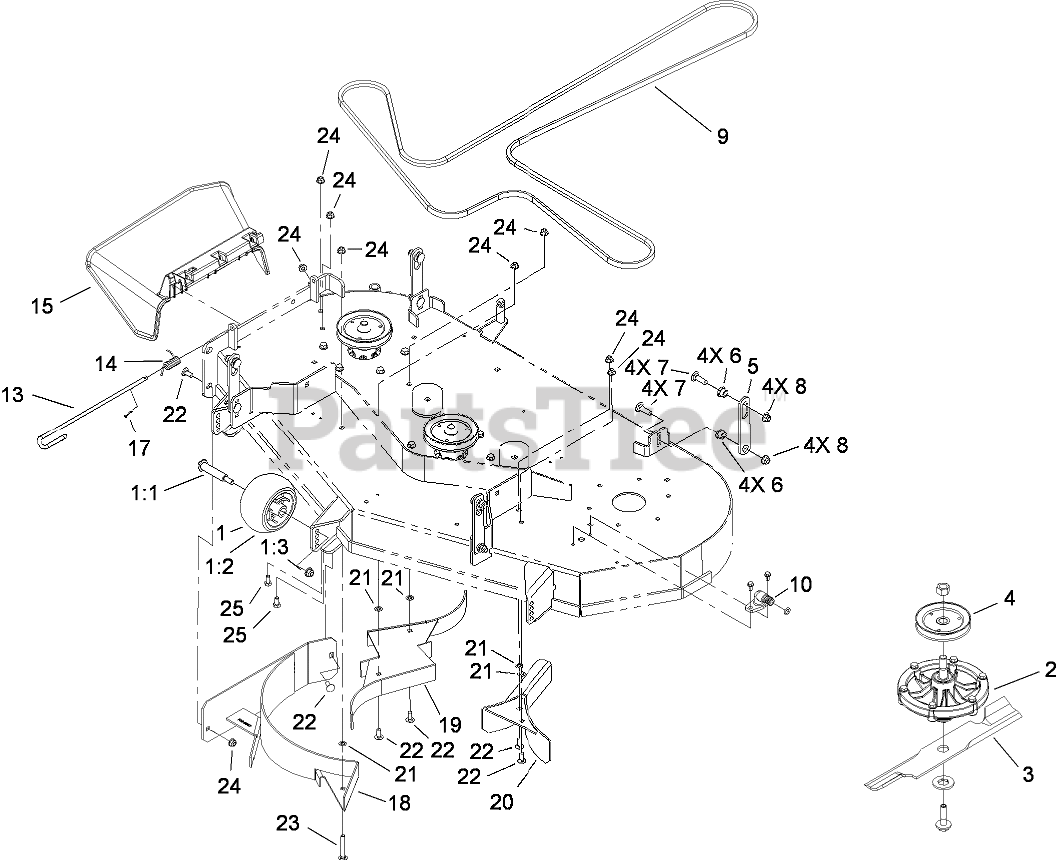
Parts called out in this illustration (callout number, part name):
1	ANTI-SCALP ROLLER KIT
1:1	BOLT-SHOULDER
1:2	ROLLER-SCALP, ANTI
1:3	NUT-HF, NI
2	COMPLETE CUTTER HOUSING ASM
3	BLADE-MULCH
4	PULLEY-DRIVE, BLADE
5	HANGER-DECK
6	BUSHING-FLANGED
7	BOLT-CARR
8	NUT-HF, NI
9	BELT
10	WASHOUT PORT KIT
13	PIN-CHUTE
14	SPRING-TORSION
15	CHUTE-DISCHARGE
17	PIN-COTTER
18	RH MULCH BAFFLE ASM
19	CENTER BAFFLE ASM
20	LH MULCH BAFFLE ASM
21	RING-RETAINING, BOLT
22	SCREW-CARR
23	BOLT-CARR
24	NUT-HF, NI
25	SCREW-HH
